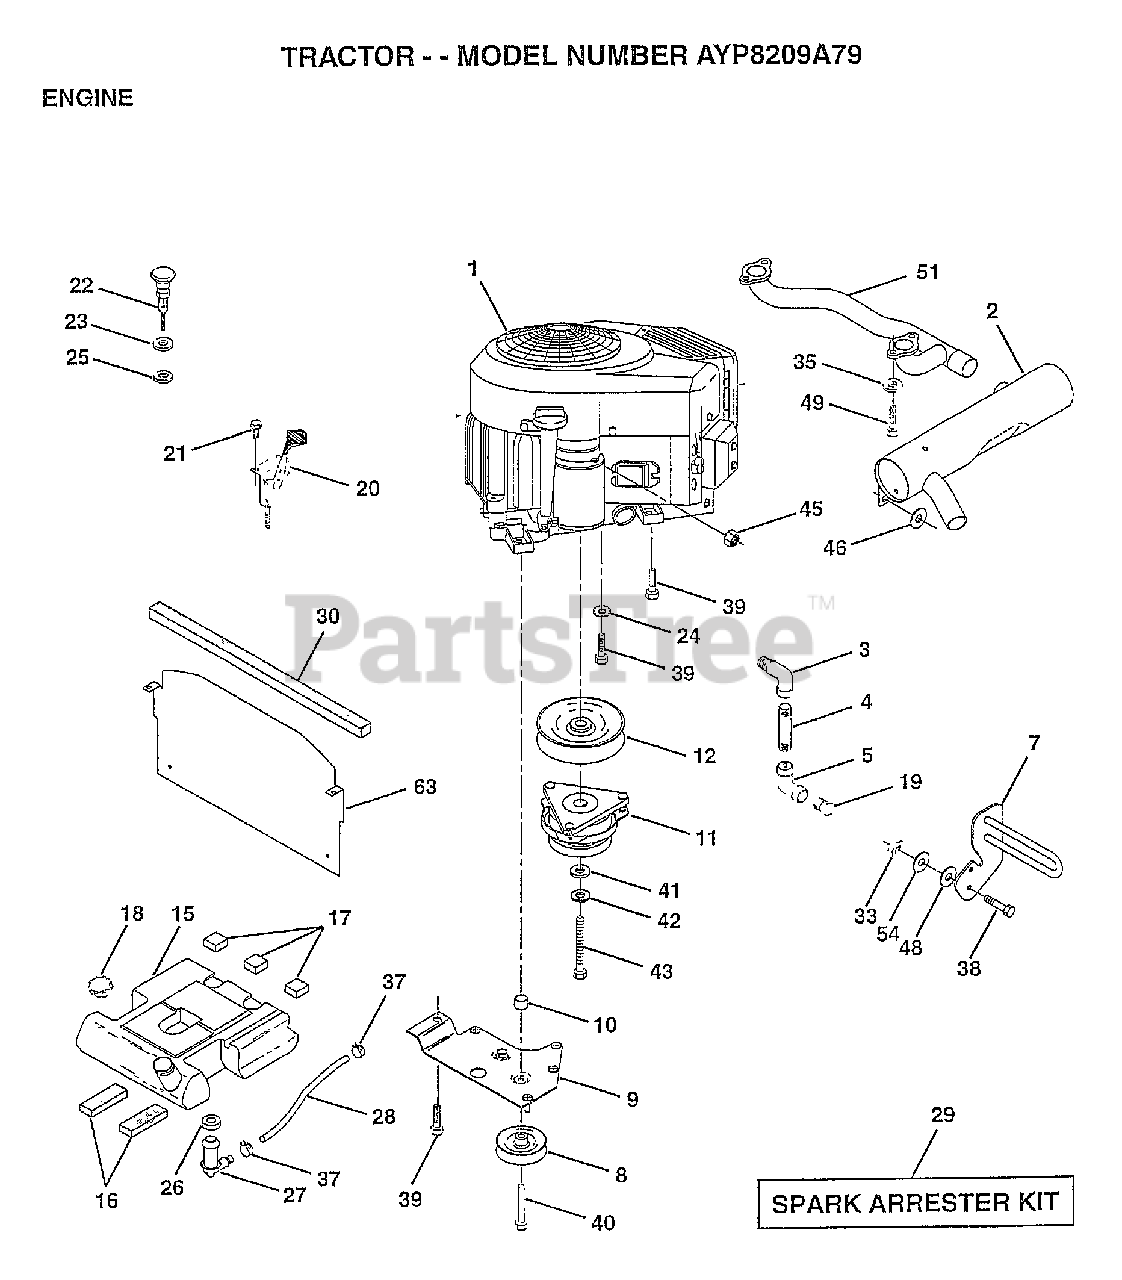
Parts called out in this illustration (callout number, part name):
3	STREET ELBOW LT
4	PIPE NIPPLE
5	ELBOW
10	BUSHING.
12	PULLEY.ENGINE.VGT
16	PAD IDLER TI
17	PAD-SPACER LT
18	CAP ASM FUEL
19	PLUG T
21	SCREW LT
23	WASHER
24	LOCKWASHER
26	BUSHING OUTLET T
27	STEM.TANK.FUEL
29	SPARK ARREST KIT
30	FOAM-STRIP LT
33	NUT
35	LOCKWASHER
37	HOSE CLAMP
38	"BOLT,HEX"
39	BOLT.HD.SOCKET.
40	SCREW.3/8-16X3.25
41	WASHER
42	LOCKWASHER
45	NUT
46	WASHER HYT
48	WASHER T
49	BOLT.HD.SOCKET.
51	PIPE.EXHAUST.B&S
54	WASHER
63	SHIELD.HEAT.VGT.
